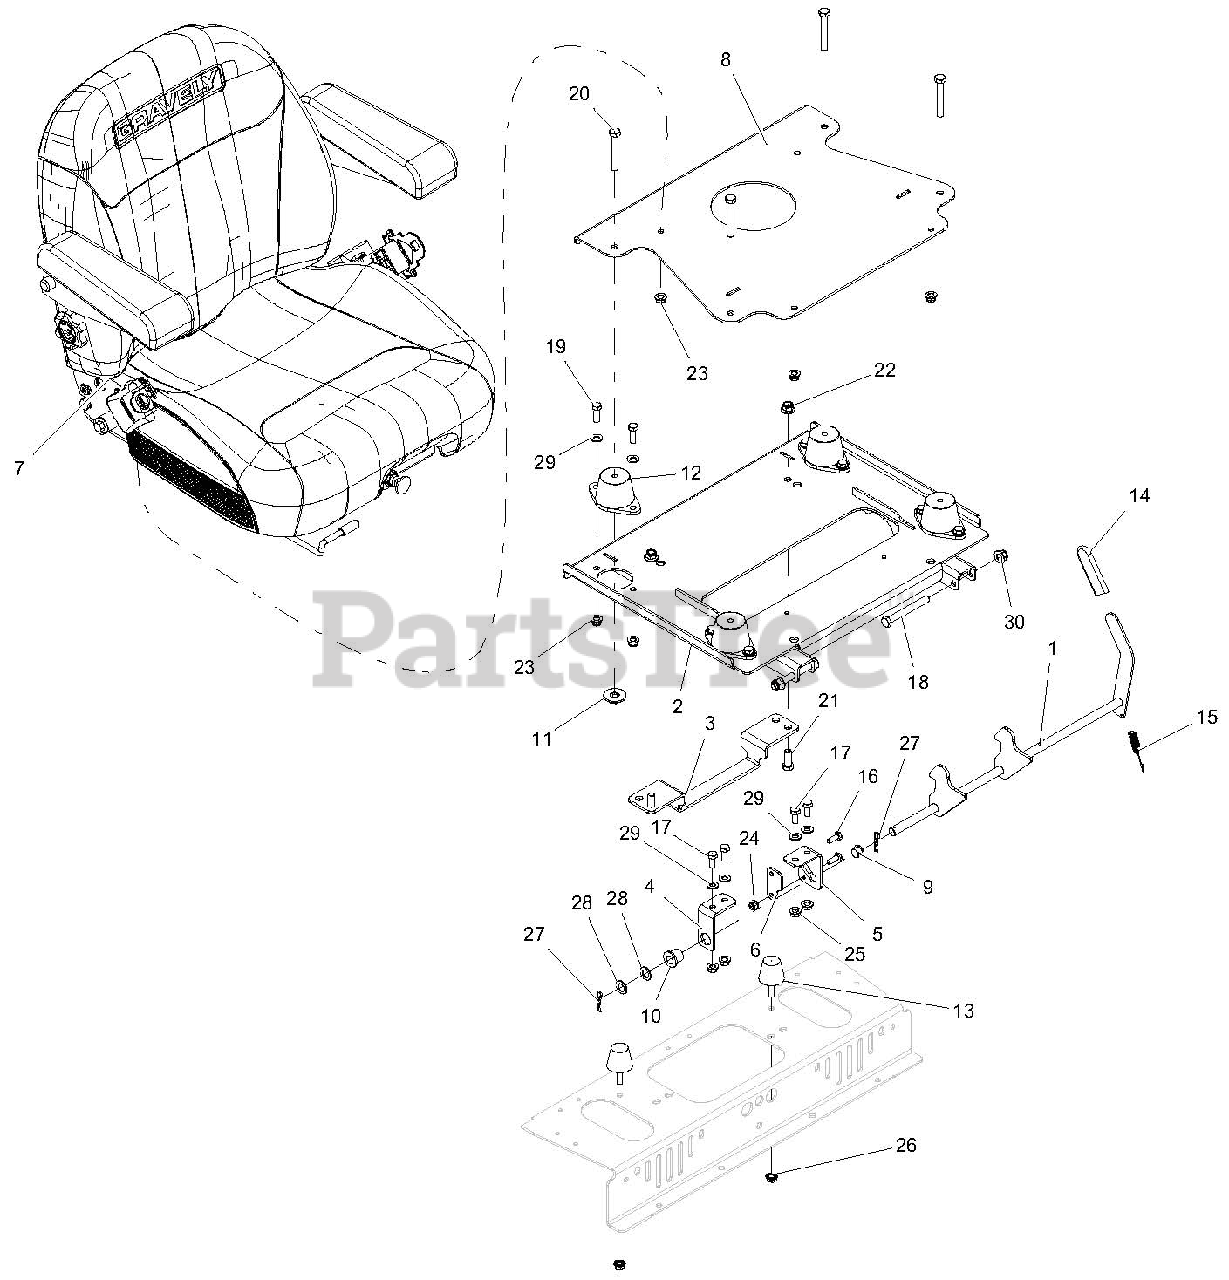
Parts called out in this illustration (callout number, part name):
1	WMT, SEAT LATCH
2	SEAT ISO MTG WMT W/SAFETY DECALS
3	BRKT, SEAT LATCH-BLACK
4	MOUNT, SEAT LATCH - RH
5	MOUNT, SEAT LATCH - LH
6	RETAINER-SEAT LATCH
7	SEAT, AIR SUSPENSION
8	WLDMT, SEAT MOUNTING
9	BUSHING, POLYLINER - .50 SPLIT
10	BSHG, FLANGE .515 X .750 X .745 X 1.00 NYLON
11	WLDMT, SEAT RETAINER
12	MOUNT, ISOLATOR
13	BUMPER, STUD MOUNTED CONE SHAPED
14	GRIP-VINYL-YELLOW .125 x 1.0 x 3.0
15	SPRG, EXTENSION
16	BLT-HEX .25-20X.75 GR5 YWZC
17	BLT-HEX .31-18X.75 GR5 YWZC
18	BLT-HEX .38-16X3.25 GR5 YWZC
19	BLT-HEX .31-18X1.00 GR5 YWZC
20	BLT-HEX .38-16X2.50 FTH GR5 YWZC
21	BLT-HEX .38-16X1.00 GR5 YWZC
22	NUT-LK-NYL-FLG .38-16 YWZC
23	NUT-LK-NYL-FLG .31-18 YWZC
24	NUT, LK-TOP-FLG .25-20 YWZC
25	NUT, LK-TOP-FLG .312-18 YWZC
26	@NUT-SPNLK-FLG .312-18 YWZC
27	PIN-HAIR INT .08X.38X1.42 YWZC
28	WSHR-FL-STL .520X.827X.062 YWZC
29	WSHR-FL-STL.344X.688X.065YWZC
30	NUT-LK-NYL-FLG .38-16 YWZC
